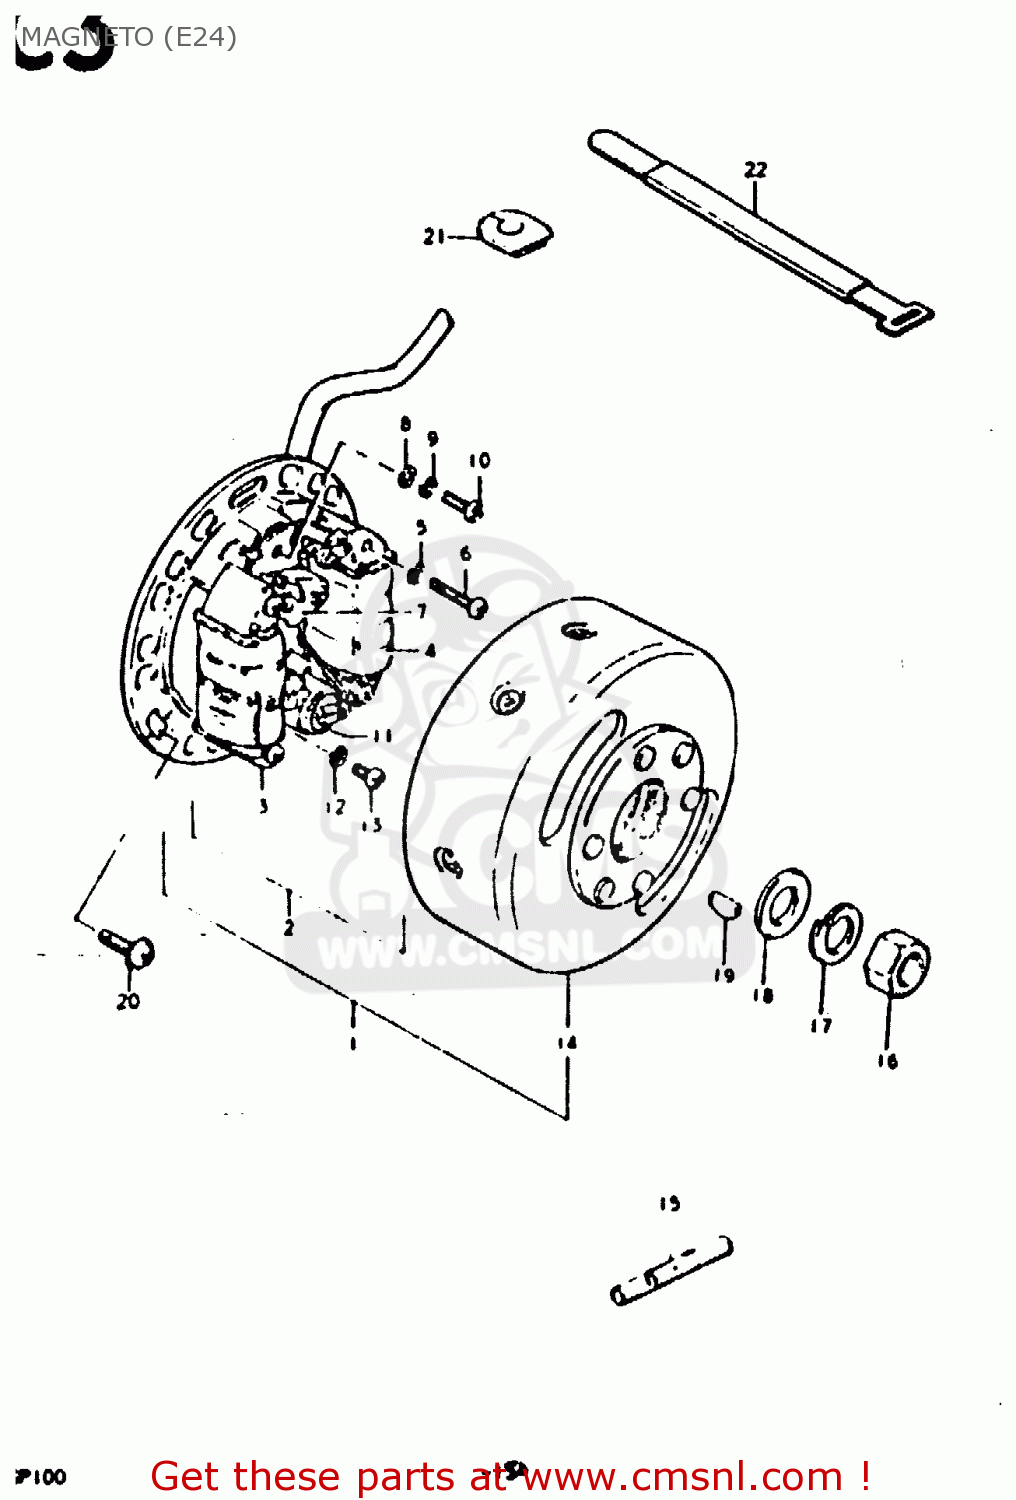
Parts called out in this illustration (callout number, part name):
1	MAGNETO ASSY
2	STARTER ASSY
3	COIL,LIGHTING
4	COIL,PRIMARY
5	LOCK WASHER
6	SCREW 4X25
7	POINT ASSY,CONTACT
8	WASHER
9	LOCK WASHER
10	SCREW(4X10)
11	CONDENSER
12	LOCK WASHER
13	SCREW 4X10
14	ROTOR
15	CONNECTOR
16	NUT (10MM)
17	LOCK WASHER
18	WASHER
19	KEY
20	SCREW(5X14)
21	GROMMET
22	CLAMP
